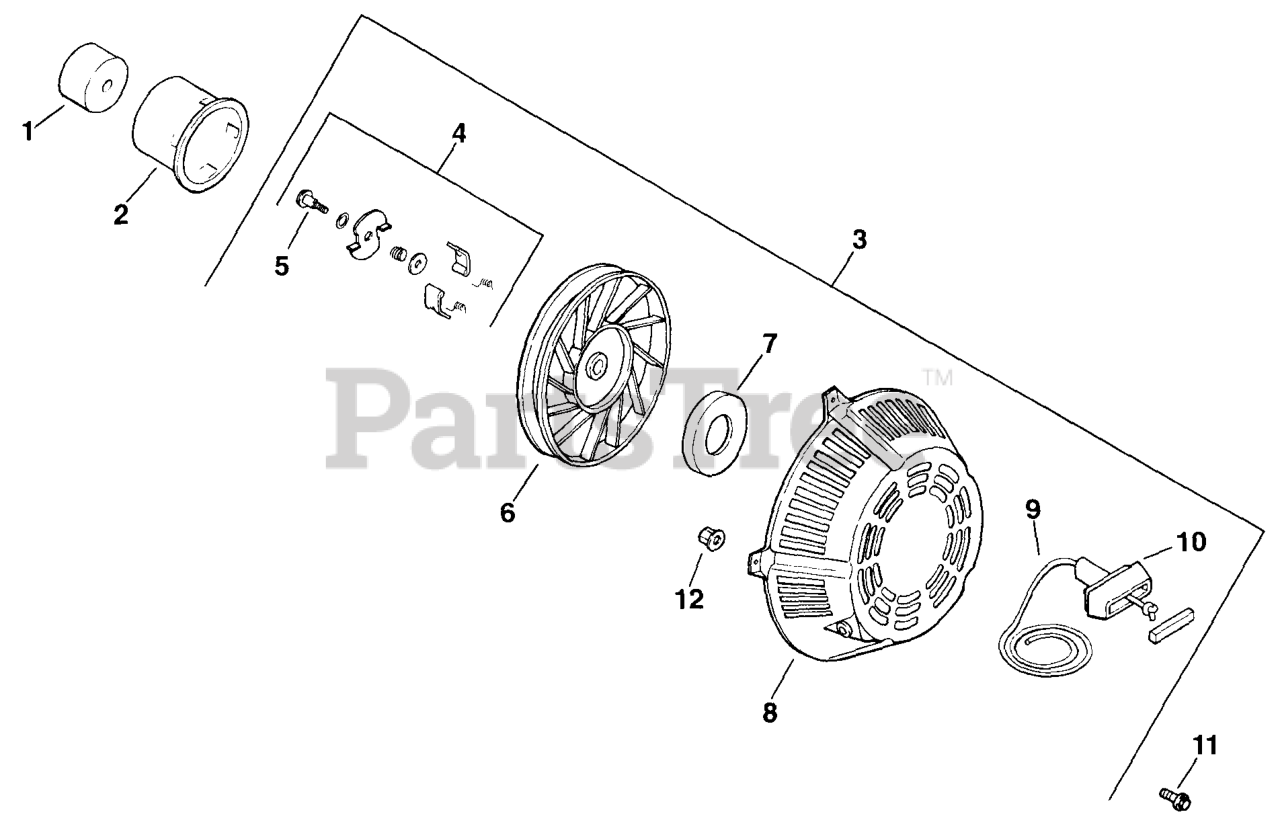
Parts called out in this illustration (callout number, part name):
1	SPACER, DRIVE CUP - DISC.
3	STARTER ASSY,RETRACTABLE-USE 12 165 03-S
4	KIT, DOG REPAIR - (#DSC)
5	SCREW - DISCONTINUED
6	PULLEY - (#DSC)
7	SPRING & KEEPER - (#DSC)
8	HOUSING - DISCONTINUED
9	ROPE - DISCONTINUED
10	HANDLE - USE 25 166 01
11	SCREW, SPECIAL HEAD
12	NUT - USE M-641060
